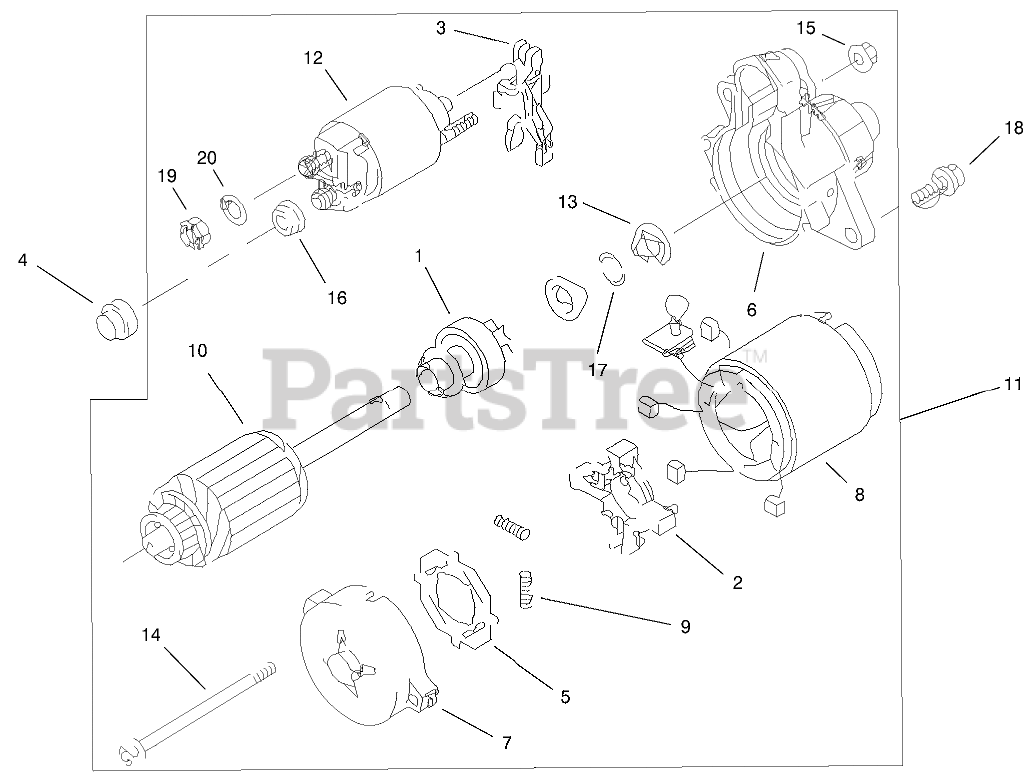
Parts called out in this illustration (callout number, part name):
1	CLUTCH ASM
2	HOLDER-BRUSH
3	LEVER-SHIFT
4	COVER
5	INSULATOR
6	COVER ASM
7	COVER ASM
8	BRUSH
9	SPRING-BRUSH
10	ARMATURE
11	STARTER - ELECTRIC
12	SWITCH ASSY
13	STOPPER
17	RING-SNAP
18	BOLT-FLANGED (8X30)
19	NUT - HEX, SMALL
20	Washer
